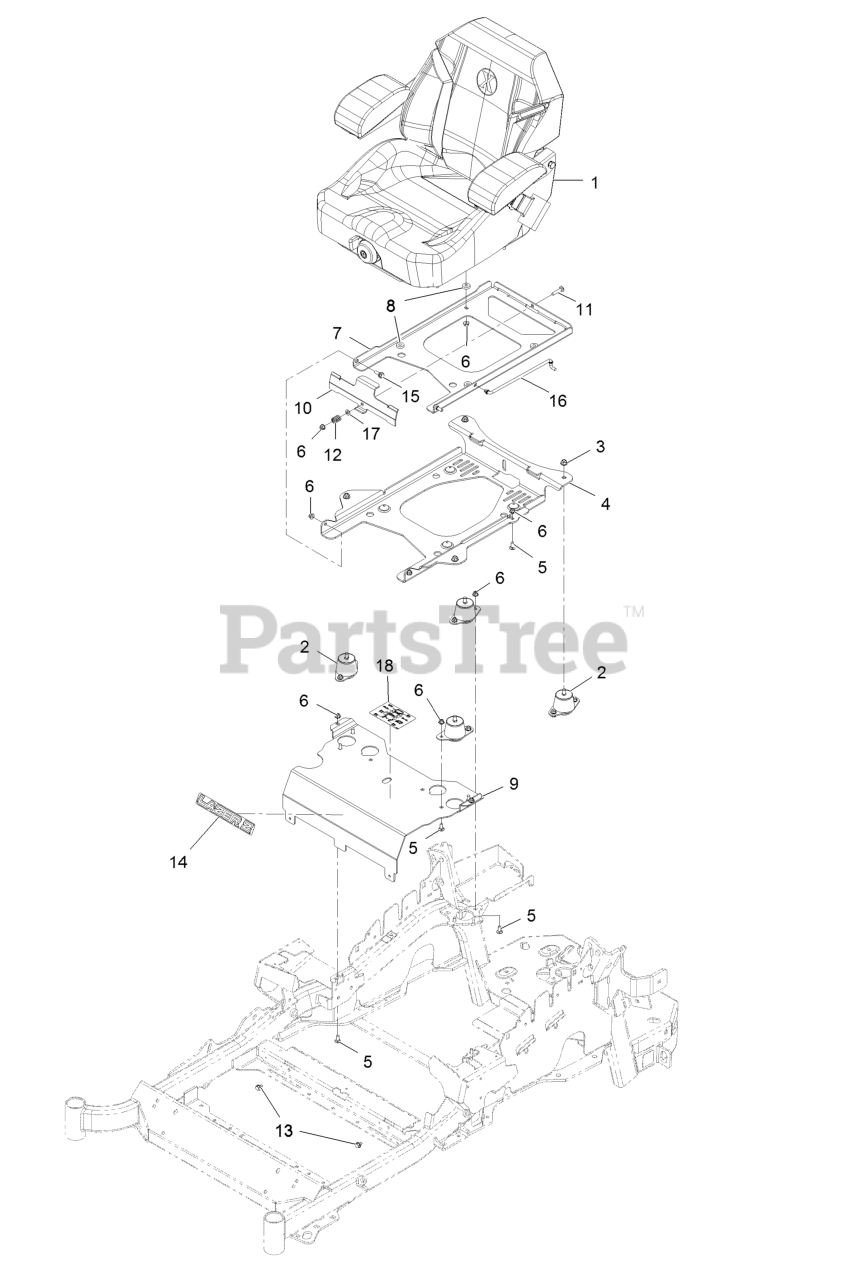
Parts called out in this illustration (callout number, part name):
1	Kit-Suspension Seat
2	Isolator-Seat
3	Nut-Nyloc 3/8-16 Flg
4	Plate-Tilt, Seat Support
5	Bolt-Carriage 5/16-18 X 3/4 Short Neck
6	Nut-Nyloc 5/16-18 Flg
7	Plate-Frame, Seat
8	Spacer-Pin, Mounting
9	Panel-Front, Seat Mount
10	Plate-Latch, Seat
11	Bolt-Carriage 5/16-18 X 1 1/2
12	Spring-Compression
13	Screw-HWH 5/16 X 1/2 Tf
14	Decal, Lazer Model
15	Screw-Shoulder
16	Rod-Prop
17	Washer-5/16 SAE
18	Decal-Service Aid
